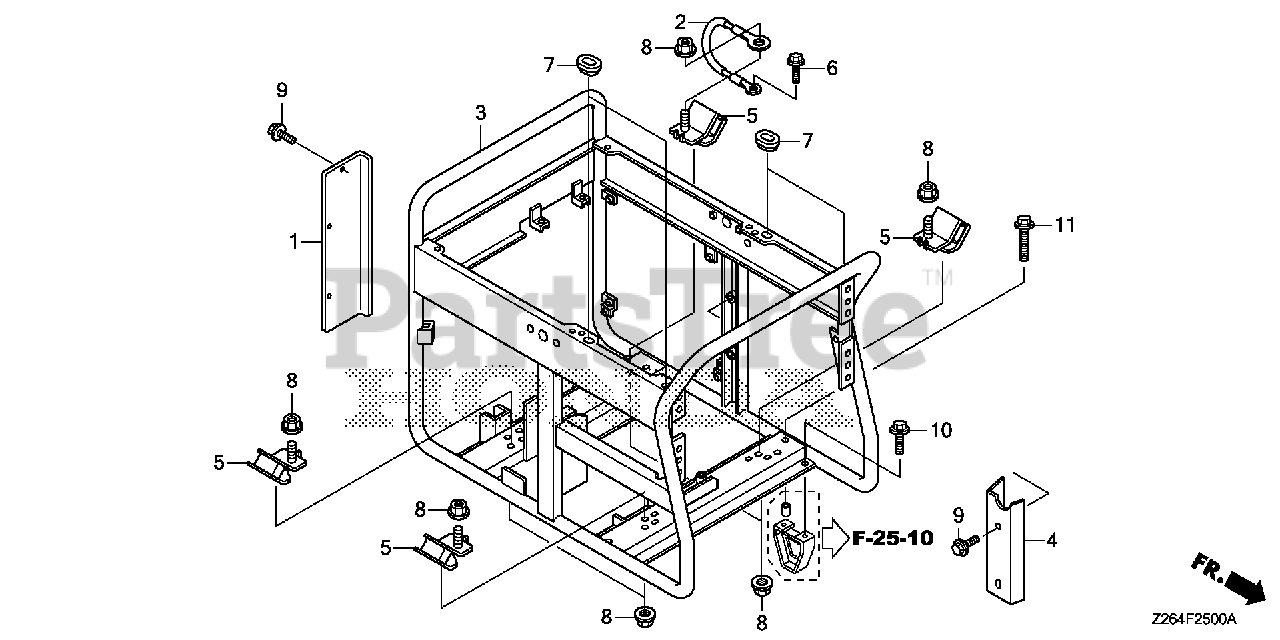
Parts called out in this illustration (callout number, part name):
1	GUARD B, CANISTER *NH105* (MAT BLACK)
2	CABLE, SUB-GROUND
3	FRAME *NH105* (COO)(FOR U.S.A.) (MAT BLACK)
4	SHROUD, SIDE FRAME
5	RUBBER (LOWER)
6	BOLT, GROUND (6X16) (WASHER 12.5MM) (ZN)
7	GROMMET, COVER
8	NUT, FLANGE (10MM)
9	BOLT, FLANGE (6X12)
10	BOLT, FLANGE (8X20)
11	BOLT, FLANGE (8X45)
